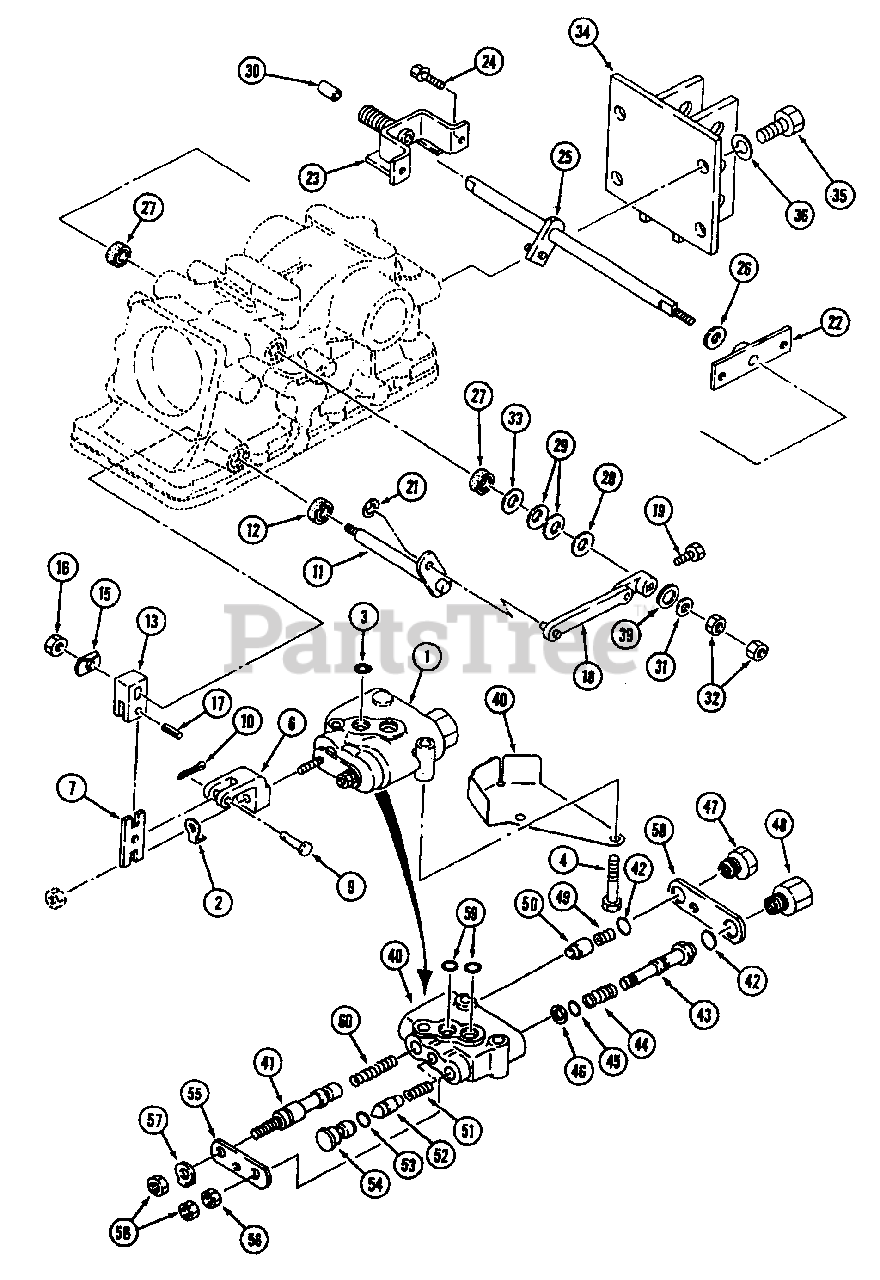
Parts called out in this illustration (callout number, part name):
1	Valve, Control
2	Plate, Stopper
10	Pin, Split
13	Shifter, Valve
26	Lining, Brake
28	Liner
34	Bracket, Top Link
40	Body Ass'y.
41	Spool
46	Ring, Back Up
49	Spring
50	Valve, Unloader
57	Plate, Stopper
60	Spring, Return
